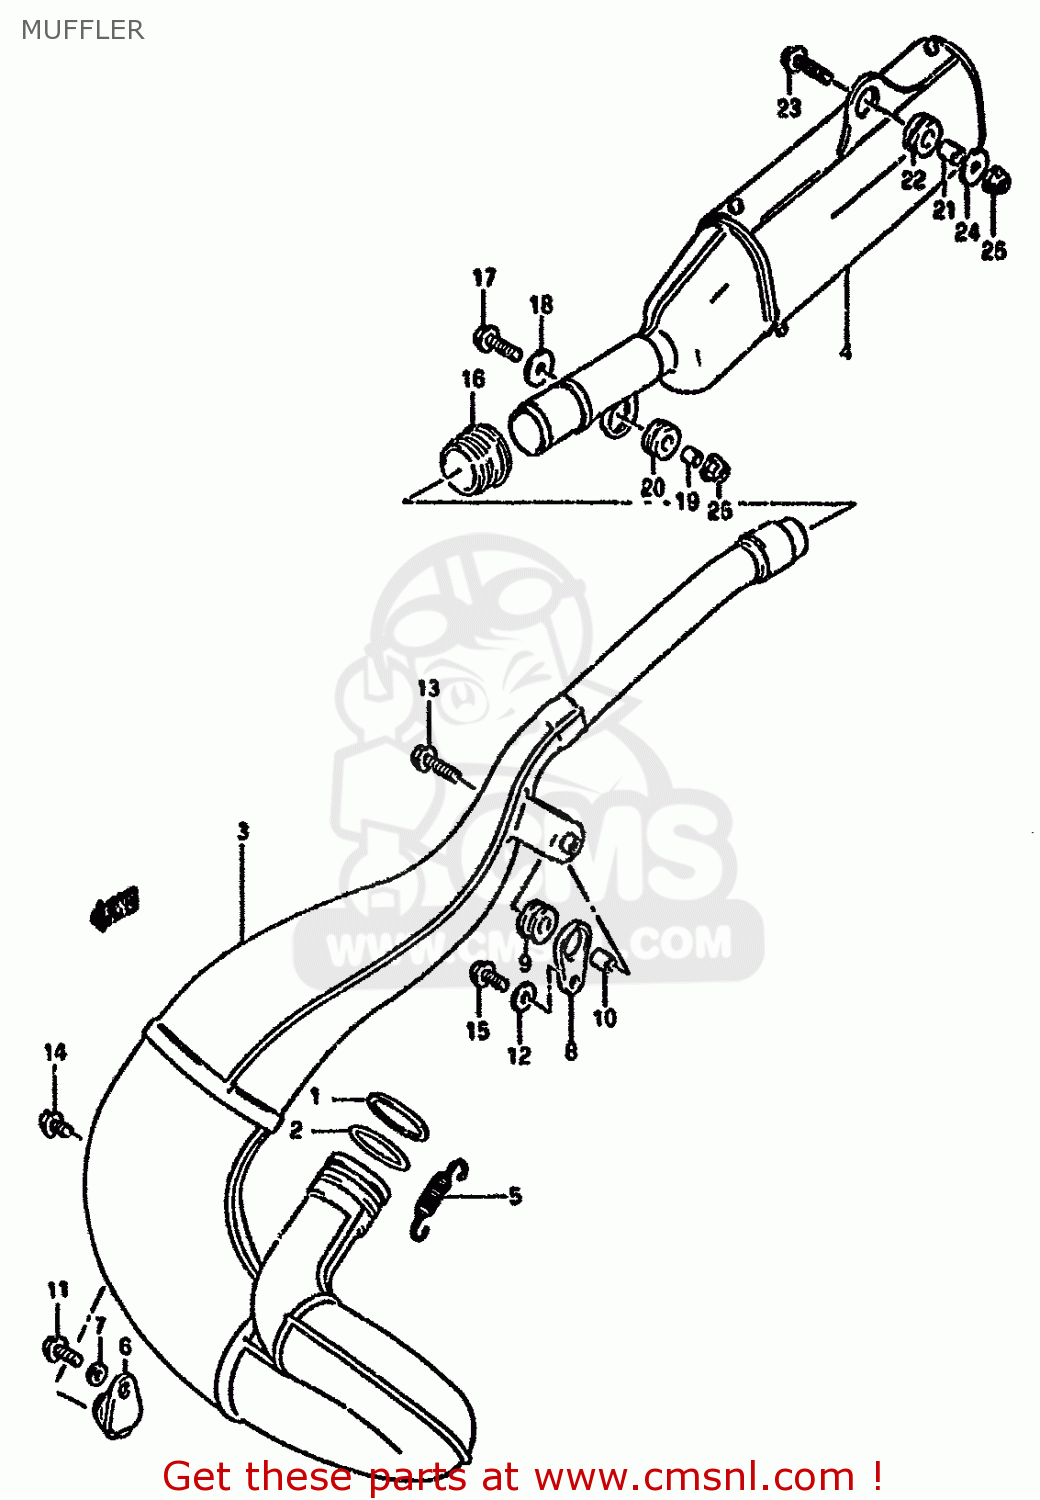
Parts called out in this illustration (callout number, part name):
1	WASHER,EXHAUST PIPE
2	O RING,EXHAUST PIPE
3	BODY,MUFFLER 1ST
4	BODY COMP,MUFFLER,SECOND.
5	SPRING
6	DAMPER,MUFFLER SUPPORT
7	WASHER
8	PLATE,MUFFLER MTG
9	CUSHION,MUFFLER
10	SPACER (6.4X9X13.5)
11	BOLT
12	WASHER(6.5X16X1.2)
13	BOLT
14	BOLT
15	BOLT
16	CONNECTOR,MUFFLER
17	BOLT
18	WASHER (8.5X29X1.6)
19	SPACER(8X10X11)
20	CUSHION
21	SPACER(8.1X11.5X13)
22	CUSHION
23	BOLT 8X30
24	WASHER (8.5X29X1.6)
25	NUT
